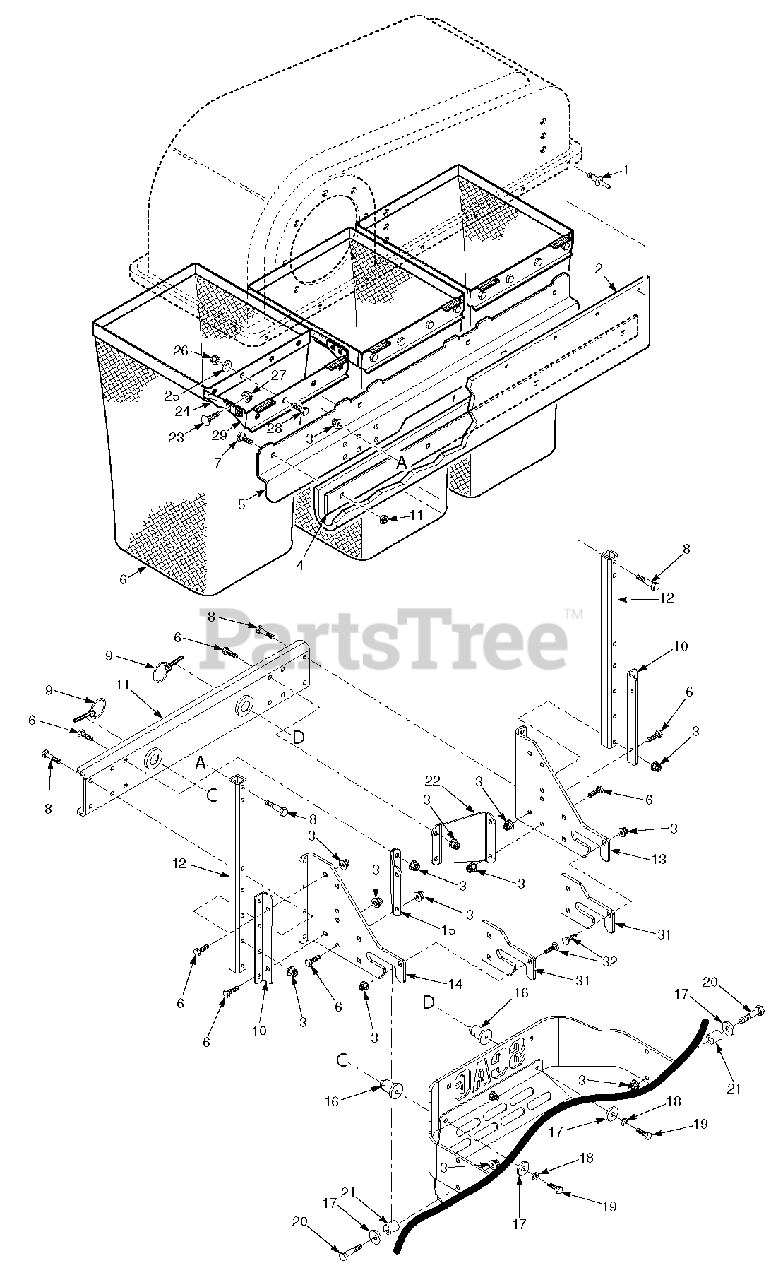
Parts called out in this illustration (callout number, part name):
1	Pop Rivet, 3/16 x .652
2	Seal, Hood
3	Nut, Elastic Flange 3/8-16
4	Retainer, Seal
5	Support, Bag Frame
6	Bag Assembly
7	Bolt, Carriage 1/4-20 x 3/4"
8	Bolt, Hex Head 3/8-16 x 2-1/4"
9	Quick Pin
10	Mounting Bracket, Tube
11	Mounting Bracket Weldment
12	Tube, Upright
13	Mounting Bracket, GC R.H.
14	Mounting Bracket, GC L.H.
15	Angle Bracket, GC
16	Pin, GC Locator
17	Flatwasher, 3/8-.406 x 1.50 x 7 Ga.
18	Lockwasher, 3/8"
19	Bolt, Hex Head 3/8-16 x 1-1/4"
20	Bolt, Hex Head 3/8-16 x 2-1/4"
21	Spacer
22	Angle Bracket, GC
23	Bolt, Carriage 5/16-18 x 3/4"
24	Tube, Bag Support
25	Flatwasher, 5/16-.375 x .875 x .083
26	Nut, Elastic Stop 5/16-18
27	Nut, Serrated Flange 5/16-18
28	Bolt, Hex Head 5/16-18 x 3/4"
29	Mount, Bag Frame Tube
30	Lock Nut, 1/4-20 Center Lock
31	Wear Plate, GC
32	Bolt, Carriage 3/8-16 x 1-1/4"
